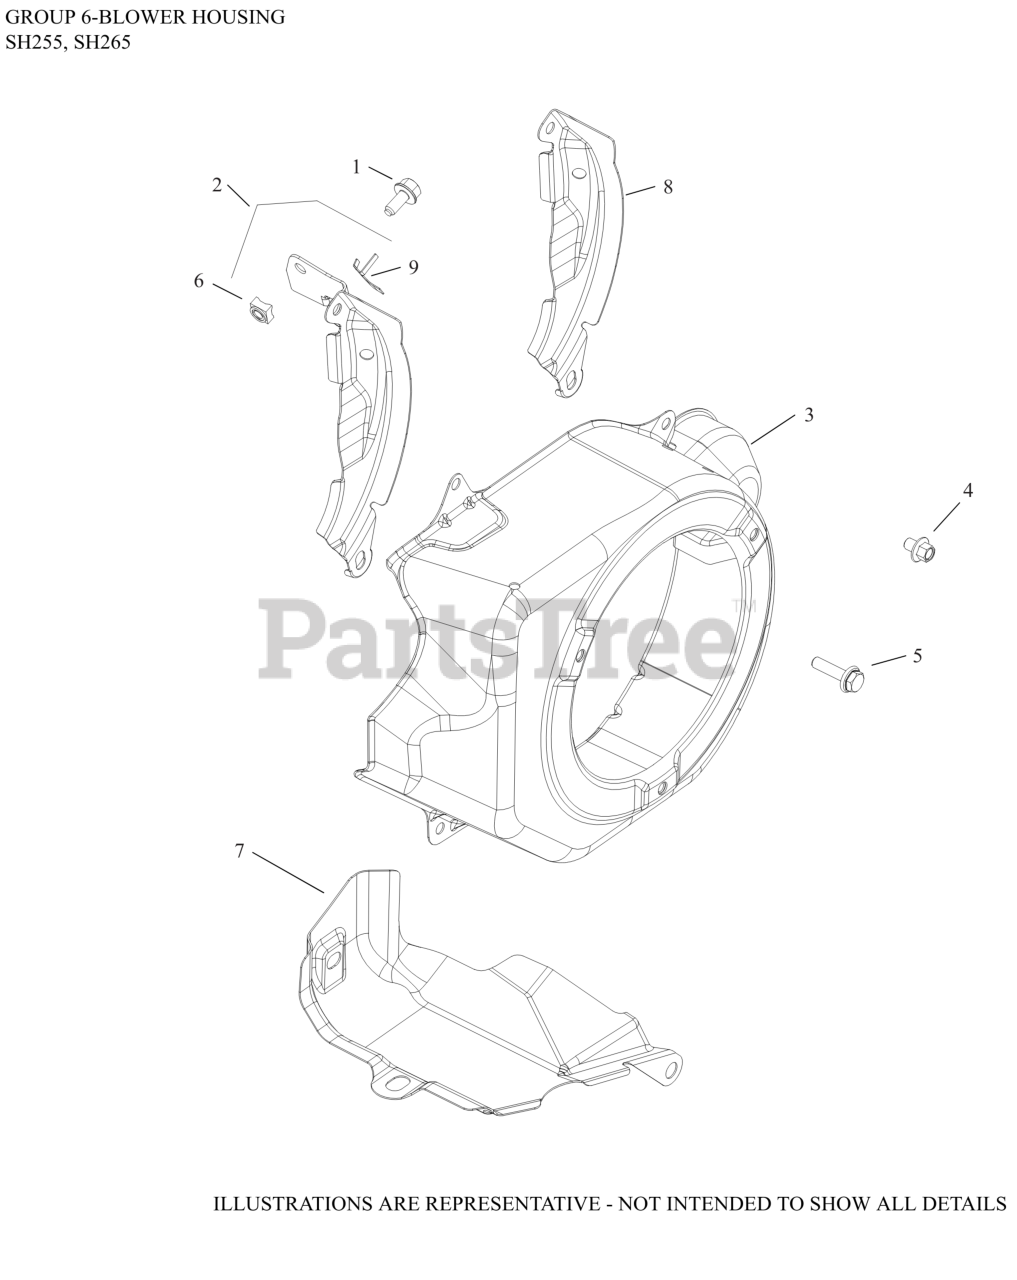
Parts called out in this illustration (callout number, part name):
1	SCREW, HEX FLANGE (M6)
2	COVER, HOUSING LOWER BLOWER ASSEM
3	HOUSING, BLOWER ASSEMBLY
4	SCREW, M6 X 8 HEX FLANGE HEAD
5	SCREW, M6 X 22
7	KIT, CYLINDER SHIELD
